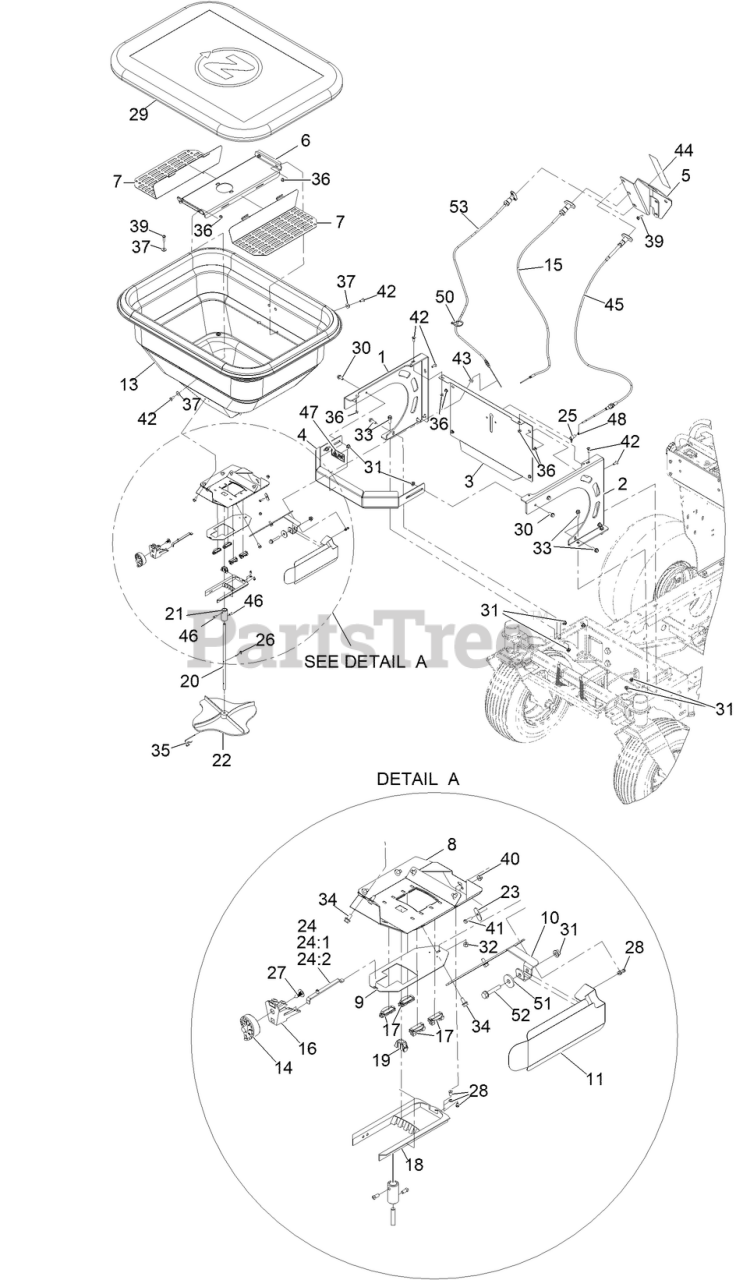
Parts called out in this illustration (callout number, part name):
1	Side-Hopper, Rt
2	Side-Hopper, Lt
3	Backshield-Hopper
4	BUMPER-FRONT, HOPPER
5	Mount-Speedometer
6	PAN-HOPPER, 220
7	SCREEN-HOPPER, 220
8	BASE PLATE, HOPPER, 220
9	SLIDE-DOOR, HOPPER
10	MOUNT-DEFLECTOR, SIDE
11	Deflector-Side, Spreader
13	ASY-HOPPER 220 LB
15	CABLE-PUSH/PULL
16	MOUNT-DIAL
17	GUIDE-RATE, GATE
18	DIFFUSER
19	HOPPER BOTTOM BEARING
20	SHAFT-HOPPER, 220
21	COUPLER-SS
22	Spinner-Spreader
23	RETAINER, CABLE
24	RATE GATE LINK ASM
24:1	LINK-GATE, RATE
24:2	SCREW-SHOULDER, SLOTTED
25	BALL JOINT-SS
26	WIRE-AGITATOR
27	Footpad Fastener
28	WIRE-STOP
29	COVER-HOPPER, LARGE
30	SCREW-HHF
31	Nut-Hex Flange
32	Nut,NYL Lock,#10-32,ST/ST 18-8
33	SCREW-HHF
34	SCREW-HHF
35	Clip-Spinner
36	Nut-Hex Flange
39	Screw-Hsbhf
40	Nut-Hex Flange
41	SCREW-HH
42	Screw-Hsbhf
43	Grommet-Rubber
44	Decal-Hopper Control
45	CABLE-PUSH/PULL
46	Screw-SQH
47	Decal-Dismemberment Hazard
48	Nut,Hex Jam Mch Scr,10-32,Sst
51	WASHER
52	Screw-HHF
53	Cable-Control, Turn Lock 2.00 Trvl
